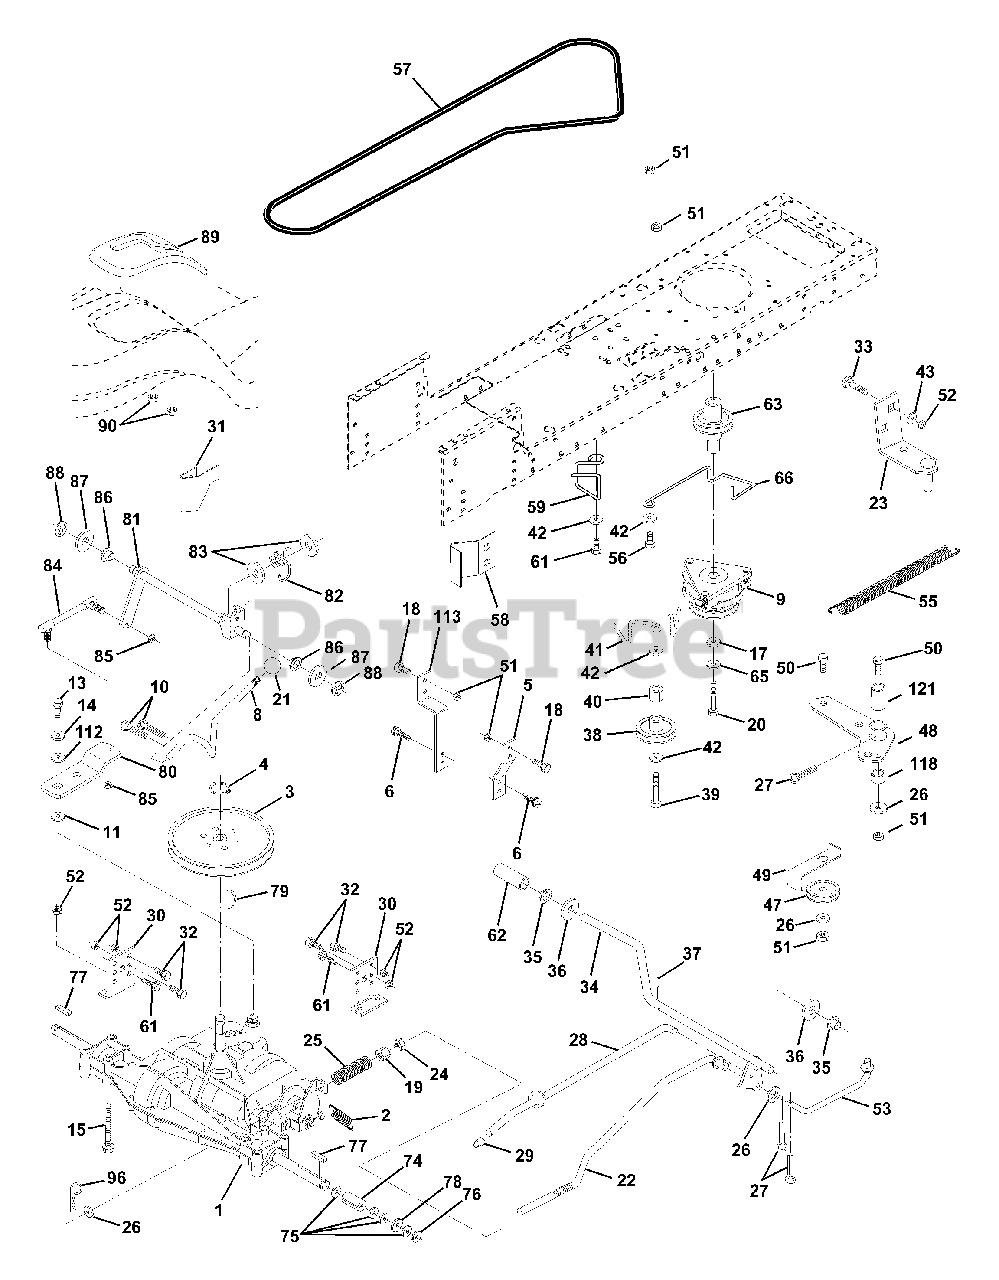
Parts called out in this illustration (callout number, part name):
2	Spring Return Brake T/a Zinc
3	Pulley Transaxle 18" tires
4	Ring Retainer # 5100-62
5	Strap Torque 30 Degrees
6	Screw Thdrol 5/16-18 X 3/4 TYT
8	Rod Shifter
9	Clutch Elect 105 Ft/lb
10	Pin Cotter 1/8 X 1 Cad
11	Washer Plate Shf 388 Sq Hole
13	Bolt 1/4-28 Unf Gr 8 W/Patch
14	Washer Lock Hvy Helical 1/4
15	Bolt Hex 5/16-18 Gr. 5
17	Washer 1-1/2 OD x 15/32 ID x .250
18	Bolt, Fin Hex 3/8-16 UNC x 1 Gr. 5
19	Nut Lock 3/8-16 Unc
20	Bolt Hex 7/16-20 x 4-1/4 5 Ga 1.38
22	Rod Brake Blk Zinc 26 840
23	Bracket Asm Mtg CL
24	Nut Hex Jam 3/8-16 Unc
25	Spring Rod Brake 2 00 Zinc
26	Washer 13/32 X 13/16 X 16 Ga
27	Pin Cotter 1/8 X 3/4 Cad
28	Rod Brake Parking LT/YT
29	Cap Brake Parking Black
30	Bracket Mtg Transaxle
31	Keeper Belt LH LT 14 Ga
32	Bolt Hex Hd 5/16-18unc X 3/4
33	Bolt RDHD SQNK 5/16-18 UNC x 3/4
34	Shaft Asm Pedal Foot
35	Bearing Nylon Blk 629 Id
36	Washer 21/32 X 1 X 16 Ga
37	Pin Roll 3/16 X 1"
38	Pulley Idler Flat
39	Bolt Fin Hex 3/8-16unc X 2-3/4
40	Spacer Split 395 X 59 Bzp
41	Keeper Belt Retainer Idler Foolproof
42	Washer 13/32 X 13/16 X 12 Ga
43	Washer 11/32 x 5/8 x 12 Ga.
47	Pulley Idler V Groove Plastic
48	Bellcrank Asm
49	Retainer Belt Style Spring
50	Bolt Hex Hd 3/8-16unc X 1-1/2
51	Nut Crownlock 3/8-16 Unc
52	Nut Crownlock 5/16-18 Unc
53	Link Clutch
55	Spring Return Clutch 6 75
56	Bolt Fin Hx 3/8-16 X 1/4
57	V-Belt Ground Drive 95 25
58	Keeper Belt RH LT Pnt/zinc 16g
59	Keeper Belt Span Ctr
61	Screw Thdrol 3/8-16x3/4 Ty-tt
62	Cover Pedal Deluxe
63	Engine Pulley LT/YT
65	Washer Lock Hvy Hlcl Spr 7/16
66	Keeper Belt Engine Foolproof
74	Spacer Axle
75	Washer 25/32 X 1 1/4 X 16 Ga
76	E-ring #5133-75
77	Key Square 2 0 X 1845/ 1865
78	Washer 25/32 X 1-5/8 X 16 Ga
79	Key Woodruff #9 3/16 x 3/4
81	Shaft Asm Cross 20"
82	Spring Torsion T/a
83	Washer 17/32 X 3/4 X 16 Ga
84	Rod Tie 20" P930 LT
85	Nut Lock Center 1/4 - 28 FNTHD
86	Bushing Rod Strg 629/632 Id
87	Washer 21/32 X 1-1/4 X 16 Ga
88	Ring Klip #5304-62
89	Console Shift STLT
90	Nut Self-thd Wsh-hd 1/4 Zinc
96	Retainer Spring 1" Zinc/Cad
112	Washer 9/32 x 3/4 x 10 Ga.
113	Strap Torque LT
118	Spacer Bellcrank
121	Nyliner Clutching STL
